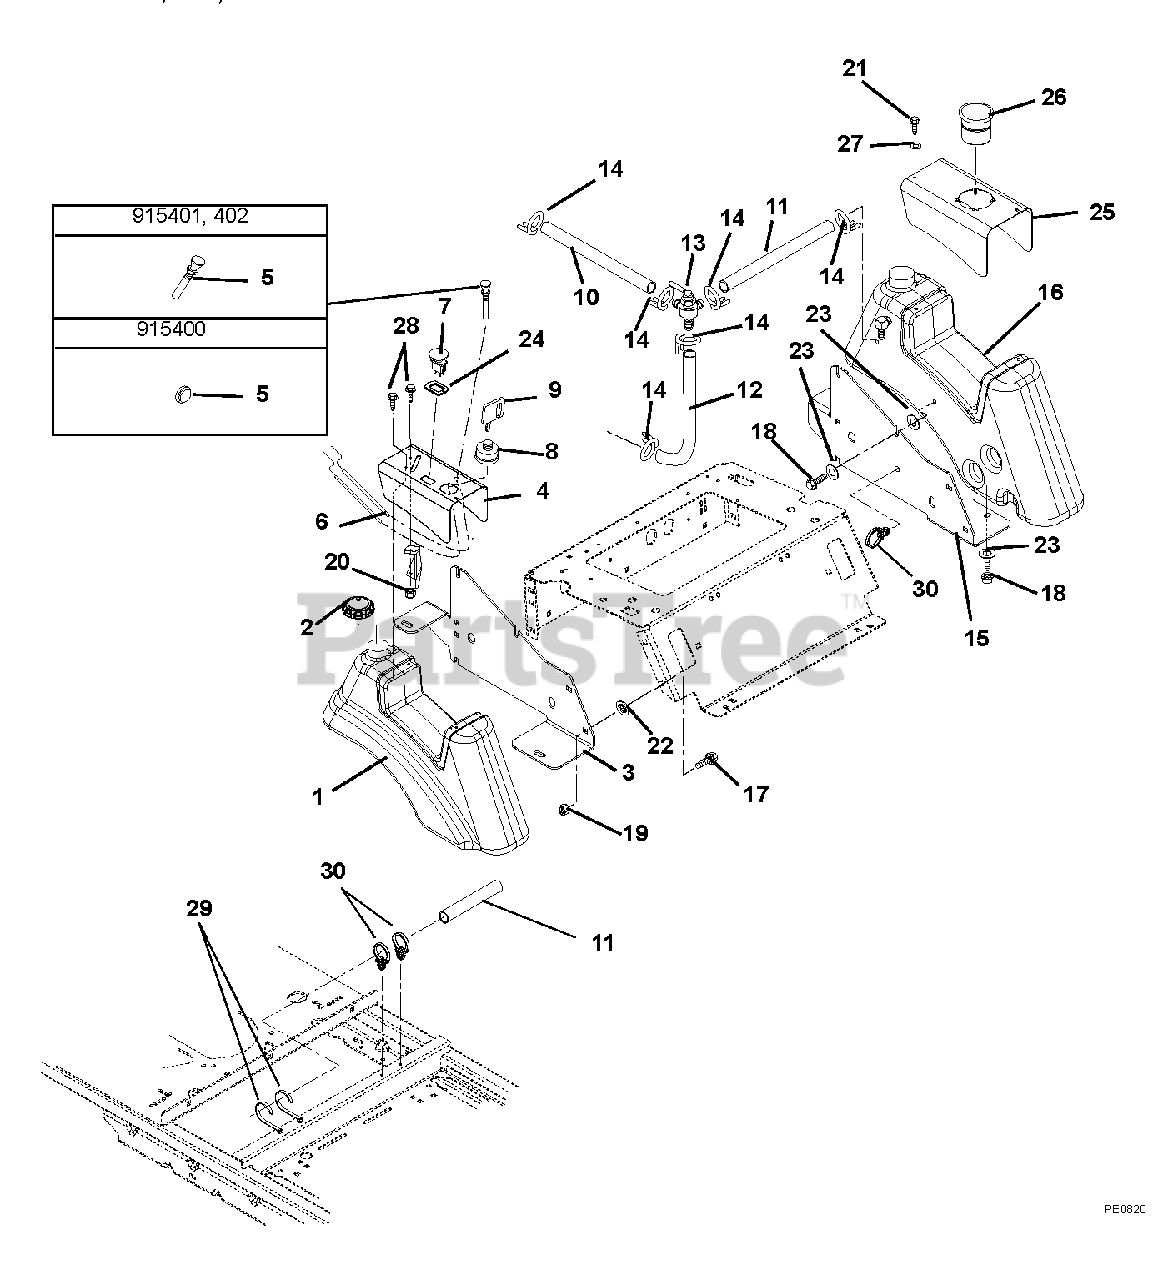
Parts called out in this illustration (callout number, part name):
1	Tank, Fuel - Right Hand
2	Fuel Cap
3	Seat Plate Right Hand
4	Right Hand Console
5	Choke Cable(401, 402)
6	Throttle Cable (401, 402)
7	Switch, Clutch
8	Key Switch
9	Key with Cap
10	Gas Line, Bulk .25 I.D. x 34 in. Long
11	Gas Line, Bulk .25 I.D. x 44 in. Long
12	Gas Line, Bulk .25 I.D. x 23 in. Long
13	Valve, Fuel
14	Clamp, Hose Wire .490/.510 x .116
15	Seat Plate Left Hand
16	Tank, Fuel - Left Hand
17	Bolt, Round Head Square Neck .38-16 x 1.00 Grade 5
18	Bolt, Serrated Hex Flange Washer Head .312-18 x .75
19	Nut .38-16 Flange Nyloc
20	Nut-Locking-Nylon 10-24 with Insert
21	Screw, Machine 10-24 x .38 Slotted Hex
22	Retainer .38 Push-On
23	Washer, Flat Steel .328 x 1.00 x .094
24	Shim, PTO Switch
25	Console, Left Hand
26	Cup Holder
27	Washer, Fender 3/16 x 3/4
28	Screw-Machine 10-24 x .50 Hex Washer Head
29	Cable Tie
30	Wire Clip
